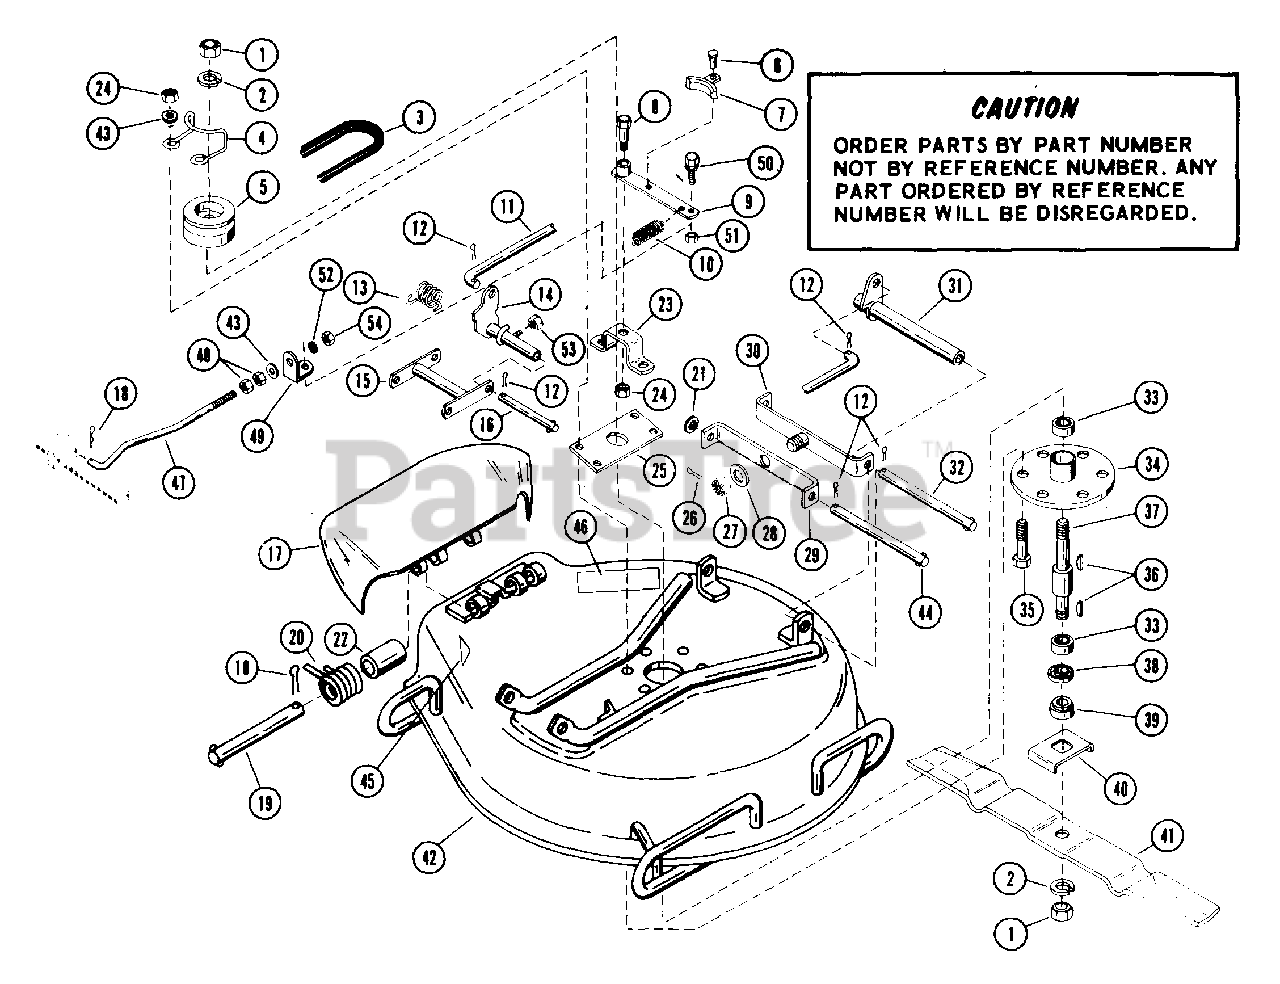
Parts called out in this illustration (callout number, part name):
1	NUT-JAM .75-10 PL
2	WSHR-LK .750X.188 MED PL
3	V-BELT, 5L-RAW EDGE
4	MOWER BELT FINGER
5	MOWER SHEAVE
6	RVT .25X.50 RH ST
7	BLADE BRAKE
8	SHOULDER BOLT .50 X 1.75
9	BLADE BRAKE ARM
10	SG-TENS .072X.51X5.31 WLD 25
11	HEIGHT LINK ROD
12	PIN-COTR .12X1.0 PL
13	SG-TORS .162X.75X.648
14	HEIGHT CONTROL ARM
15	FLOATING LINK
16	ADAPTER PIN
17	PAN CHUTE EXTENSION
18	PIN-COTR .09X.75 PL
19	CLEVIS PIN
20	SG-TORS .095X.50X 1.0
21	WSHR-FL-STL .531X1.062X.095 PL
22	BSHG-SLV .334 X .502 X 1.437
23	BLADE BRAKE SUPPORT
24	NUT-LK-CTR .375-16 GR A PL
26	PIN-COTR .12 X 1.25 PL
27	NUT-JAM-SL .625-18
28	WSHR-FL-STL .630X1.005X.062 PL
31	REAR RAISING BRACKET
32	REAR BRACKET PIN
33	BRG-BALL .751X1.78X.61
34	SPINDLE HOUSING
35	BLT-HEX .38-16X1.00 PL
36	KEY-WDRF .188X.75X.313 SAE 9
37	MOWER SPINDLE
38	BEARING SLINGER
39	RETAINER HUB
40	BLADE TRAY
41	BLADE, MOWER
42	MOWER PAN ASSEMBLY
43	WSHR-FL-STL .38X.875X.083 PL
44	HANGER PIN
45	SAFETY LABEL
46	MOWER CAUTION LABEL
47	BLADE BRAKE ROD
48	NUT-HEX .312-18
49	BRAKE ROD GUIDE
50	SCR-FLG-WHZ 10-24X.75 PL
51	NUT-LK TOP 10-24 PL
52	GROMMET
53	NUT-LK-CTR .250-20 PL
54	NUT-LK .312-18 GR A PL
